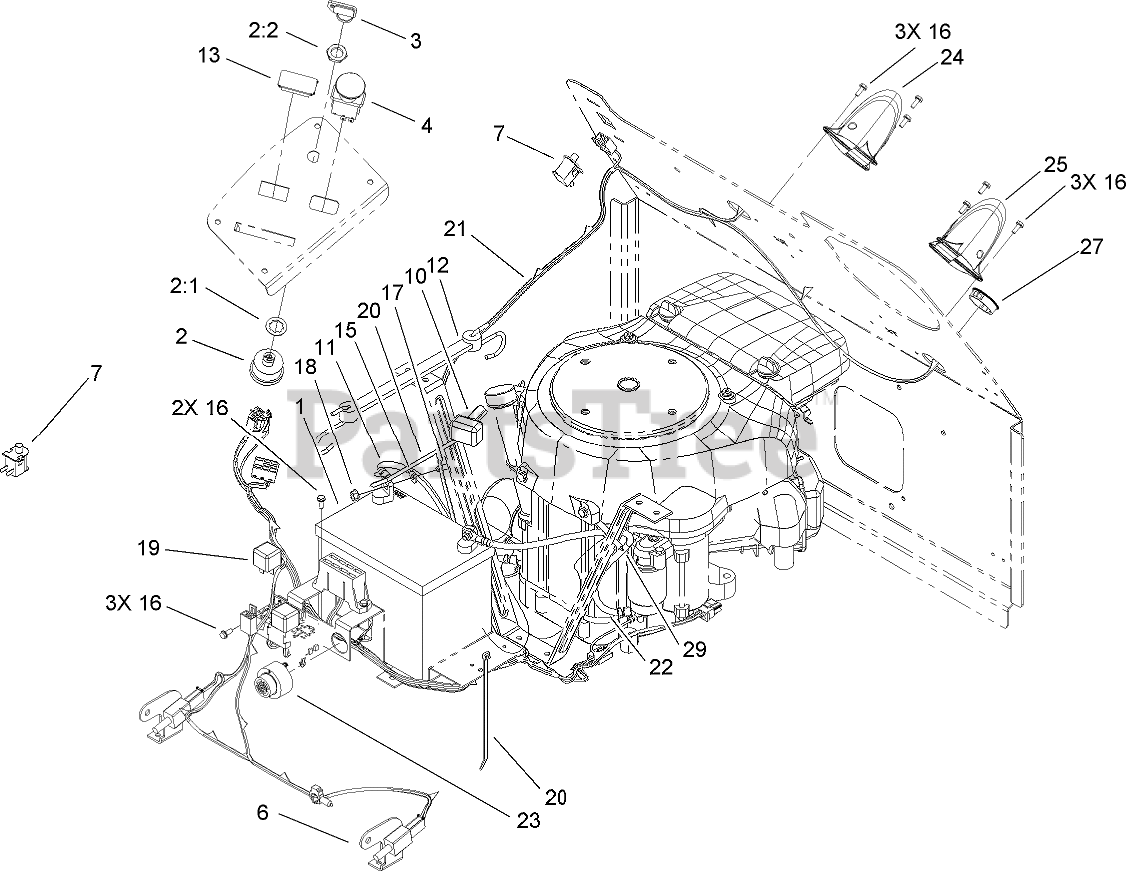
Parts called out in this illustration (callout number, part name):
1	BATTERY
2	Key Switch ASM
2:1	WASHER-TOOTH, INTERNAL
2:2	NUT-HH
3	KEY-IGNITION
4	SWITCH-PTO
6	SWITCH
7	SWITCH-BAIL
10	BOOT-INSULATOR, TERMINAL
11	CABLE-NEGATIVE, BLACK
12	HOLDDOWN-BATTERY
13	PLUG-HOLE
15	WASHER-FLAT
16	SCREW-TAPTITE
17	SCREW-HH
18	NUT-HF
19	RELAY
20	TIE-CABLE
21	HARNESS-WIRE
22	WIRE-21 INCH
23	ALARM-TONE, DUAL
24	BAG SENSOR ASM
25	BAG SENSOR ASM
27	BUSHING-HARNESS, WIRE
29	CLAMP-HOSE
